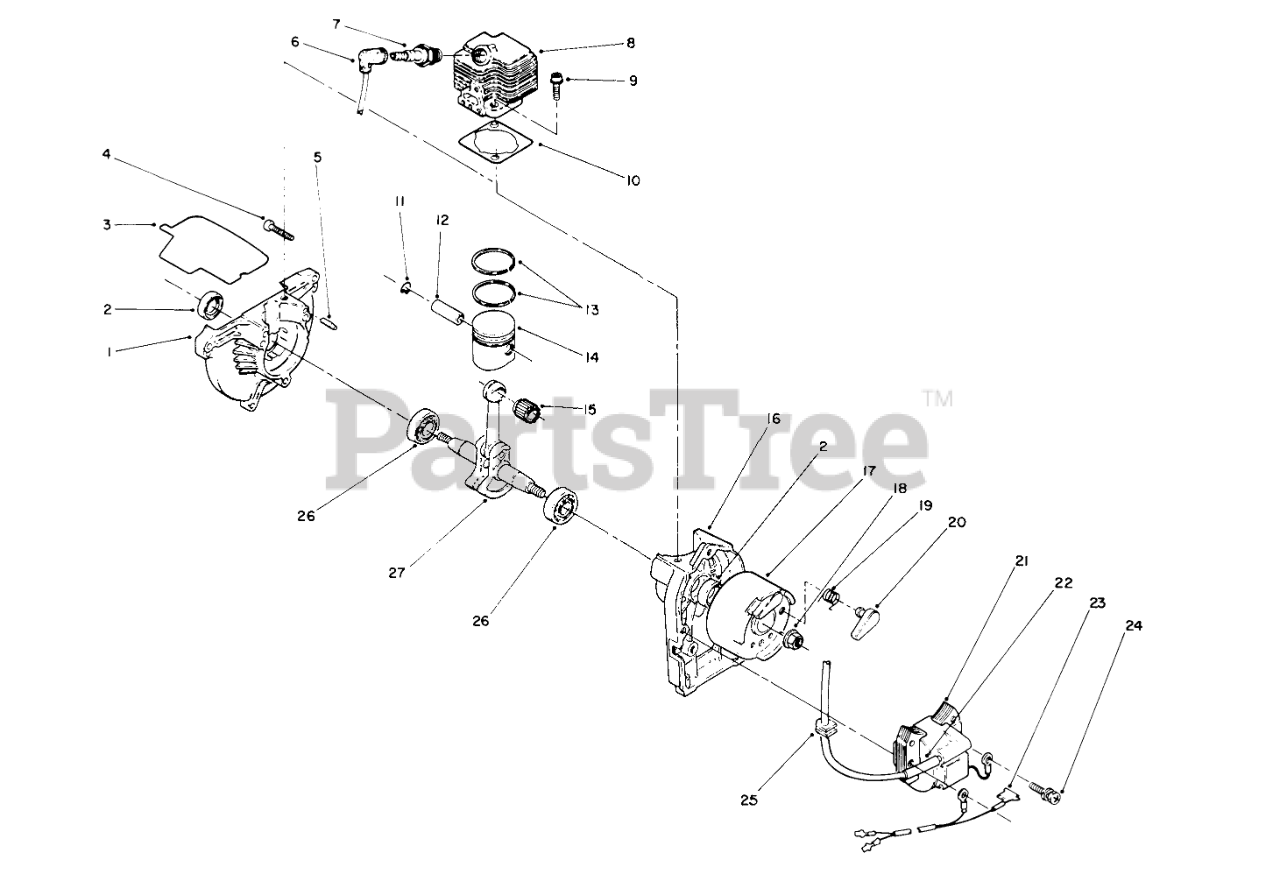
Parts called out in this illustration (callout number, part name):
1	DRIVE CASE
2	OIL SEAL
3	Gasket-Baffle
4	Screw
6	PLUG BOOT
7	Plug-Spark
8	CYLINDER
9	FLANGE BOLT
10	CYL GASKET
11	PISTON PIN CLIP
12	Pin-Piston
13	TOP RING
14	Piston (Incl. Ref. #11 & 12)
15	NEEDLE BEARING
16	STARTER CASE
17	Flywheel (Incl. Ref. #19 & 20)
19	RETURN SPRING
20	RATCHET
21	IGNITION COIL
23	LEAD WIRE
24	BOLT AND WASHER
25	GROMMET
26	BEARING
27	CRANKSHAFT ASSEMBLY
